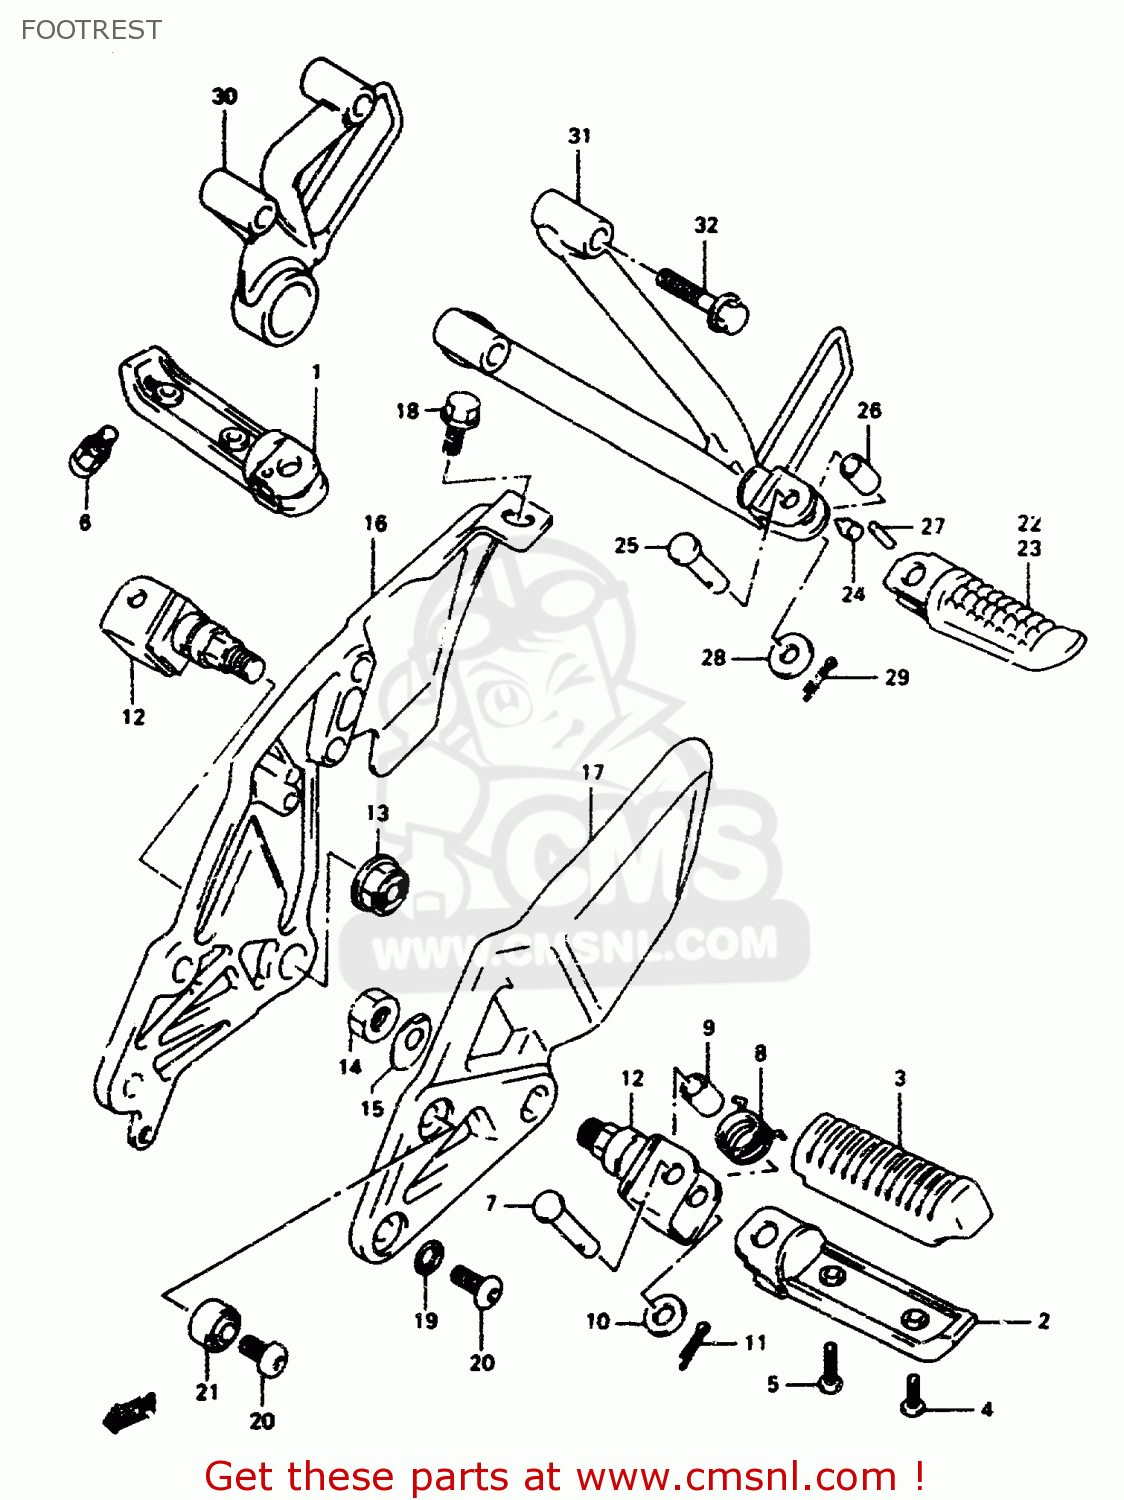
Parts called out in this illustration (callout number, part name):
1	BAR,FOOTREST,R
2	BAR,FOOTREST,L
3	RUBBER,FOOTREST
4	SCREW
5	SCREW
6	SENSOR,FOOTREST
7	PIN
8	SPRING
9	SPACER(8.1X12X22)
10	WASHER(8.5X18X1)
11	PIN 20X15
12	BOSS,FR FOOTREST
13	NUT 12MM
14	NUT
15	WASHER,FR FOOTREST
16	BRACKET,FOOTREST,R
17	BRACKET,FOOTREST,L
18	BOLT
19	WASHER
20	BOLT(8X25)
21	BUSH
22	BAR,PILLION FOOTREST R
23	BAR,PILLION FOOTREST L
24	CUSHION,FOOTREST HOLDER
25	PIN
26	SPACER(8.1X12X22)
27	PIN(4X20)
28	WASHER
29	PIN 20X15
30	BRACKET,PILLION FOOTREST
31	BRACKET
32	BOLT
